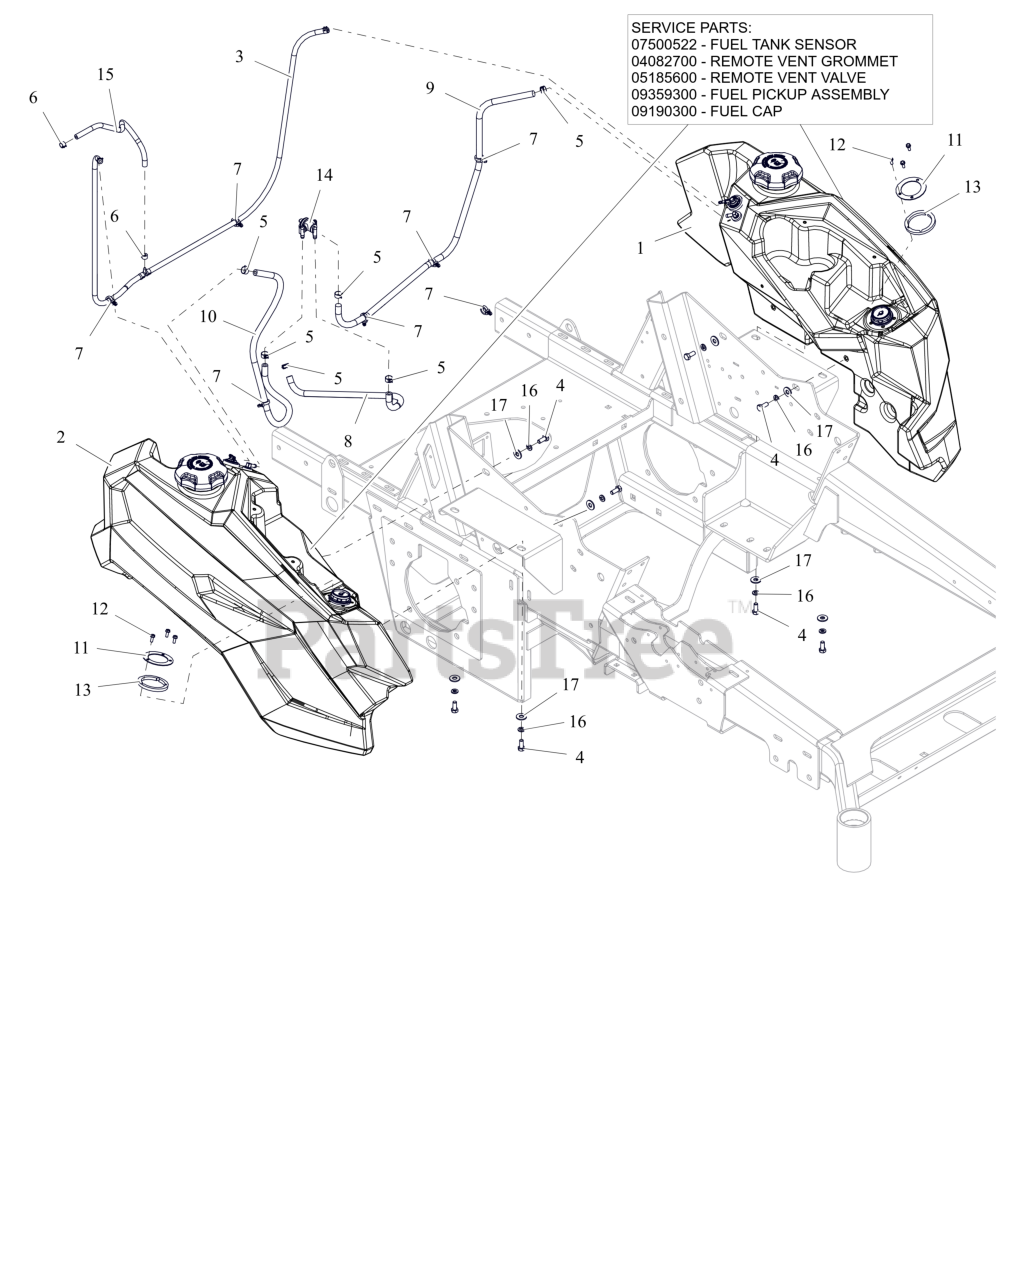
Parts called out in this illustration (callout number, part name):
1	ASM- PT300-500 LH FUEL TANK
2	ASM- PT300-500 RH FUEL TANK
3	ASM- PT300/500/600 VENT LINE
4	BLT,HEX .31-18X.75 G5 ZCC
5	CLAMP, FUEL LINE
6	CLAMP-HOSE, SPRING .188
7	CLIP- PUSH-IN X-MAS TREE CABLE
8	1 INCH OF HOSE, .25 LOW-PERM BULK GAS
9	1 INCH OF HOSE, .25 LOW-PERM BULK GAS
10	1 INCH OF HOSE, .25 LOW-PERM BULK GAS
11	RETAINER, FUEL GAUGE (BLACK)
12	SCR-MCH 10-24X.50 HWHSTAINLESS
13	SPCR, FUEL GAUGE RETAINER (BLACK)
14	VALVE, FUEL - WITH MAGNET
15	HOSE, .188 30R7 BULK
16	WSHR,LK-REG .312X.078 ZCC
17	WSHR,FLT .375X.875X.083 ZCC
